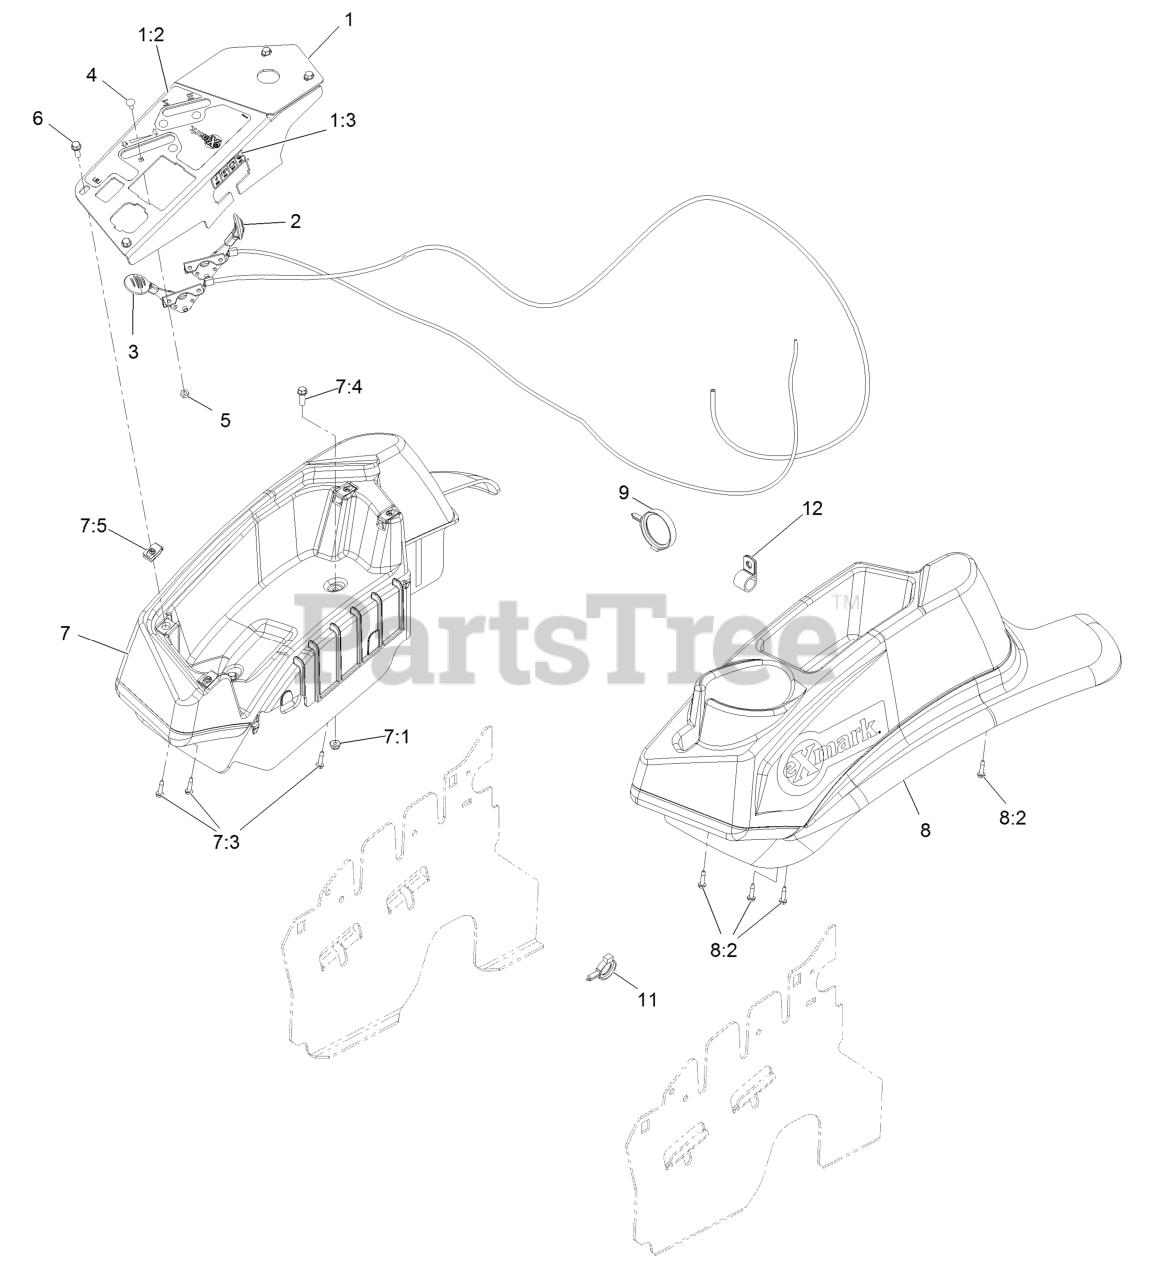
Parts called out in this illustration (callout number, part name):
1	CONSOLE,PANEL W/DECAL
1:2	DECAL-CONTROL PANEL NON-E
1:3	DECAL-FUSES
2	ASM, CHOKE CABLE
3	ASM,THROTTLE CABLE
4	BOLT-CARR
5	NUT-LOCK, NI
6	SCREW-HWH
7	CONSOLE,RH NARROW ASM
7:3	SCREW,THD FORM,HWH
7:4	SCREW-HWH
7:5	Nut-Retainer-Panel 1/4-20
8	CONSOLE.LH NARROW ASM
8:2	SCREW,THD FORM,HWH
9	CLAMP-HARNESS
11	CLAMP-HOSE
12	CLIP-LOOM
